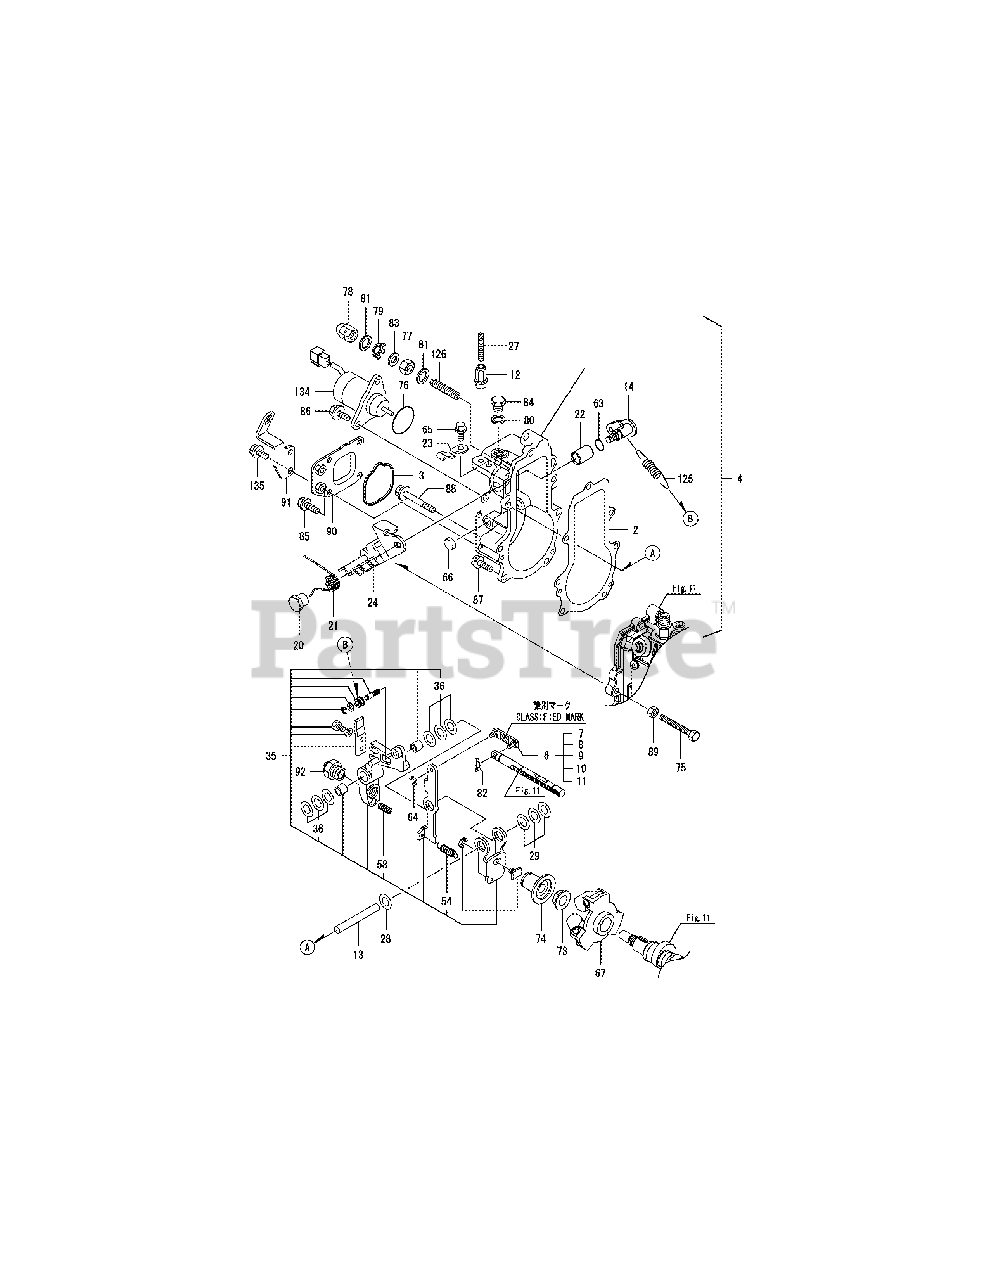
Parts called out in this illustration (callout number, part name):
4	CASE ASSY, GOVERNOR
7	LINK,CLASIFIEDMARK93
8	LINK,CLASIFIEDMARK98
9	LINK,CLASIFIEDMARK88
10	LINK,CLASIFIEDMARK00
11	LINK,CLASIFIEDMARK03
14	SHAFT ASSY, CONTROL
24	LEVER ASSY,REGULATOR
35	LEVER ASSY, GOVERNOR
36	SHIM SET, ADJUSTING
58	SPRING, FUEL CONTROL
65	BOLT 6X 10 PLATED
73	NUT, GOVERNOR WEIGHT
81	SEAL WASHER 12
85	BOLT 6X 10 PLATED
86	BOLT M 6X 14 PLATED
87	BOLT M 6X 20 PLATED
88	BOLT M 6X 45 PLATED
90	COVER, GOVERNOR CASE
125	SPRING, GOVERNOR
126	LIMITER ASSY, FUEL
134	SOLENOID, STOP
135	BOLT 6X 10 PLATED
